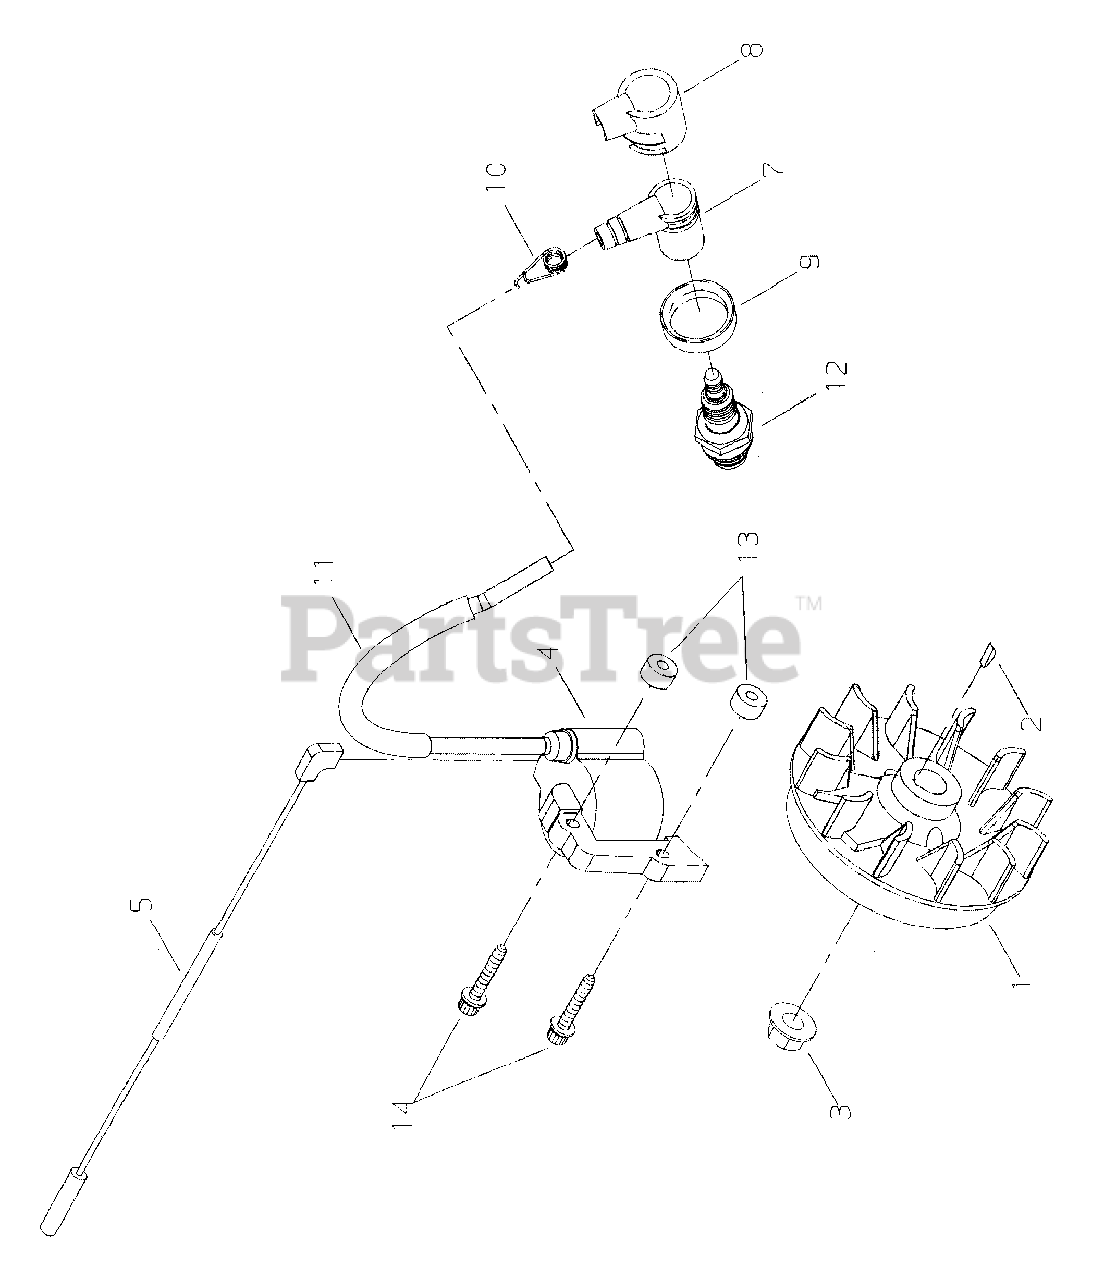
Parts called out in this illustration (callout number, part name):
1	FLYWHEEL
2	KEY - 3X10
3	NUT - 8
4	COIL, IGNITION
5	LEAD - IGNITION
7	CAP, SPARK PLUG
8	COVER, CAP
9	SEAL, DUST
10	TERMINAL, SPARK PLUG CAP
11	SLEEVE, IGNITION COIL
12	SPARK PLUG -- CJ-8Y
13	INSULATOR
14	SCREW - 4X26
